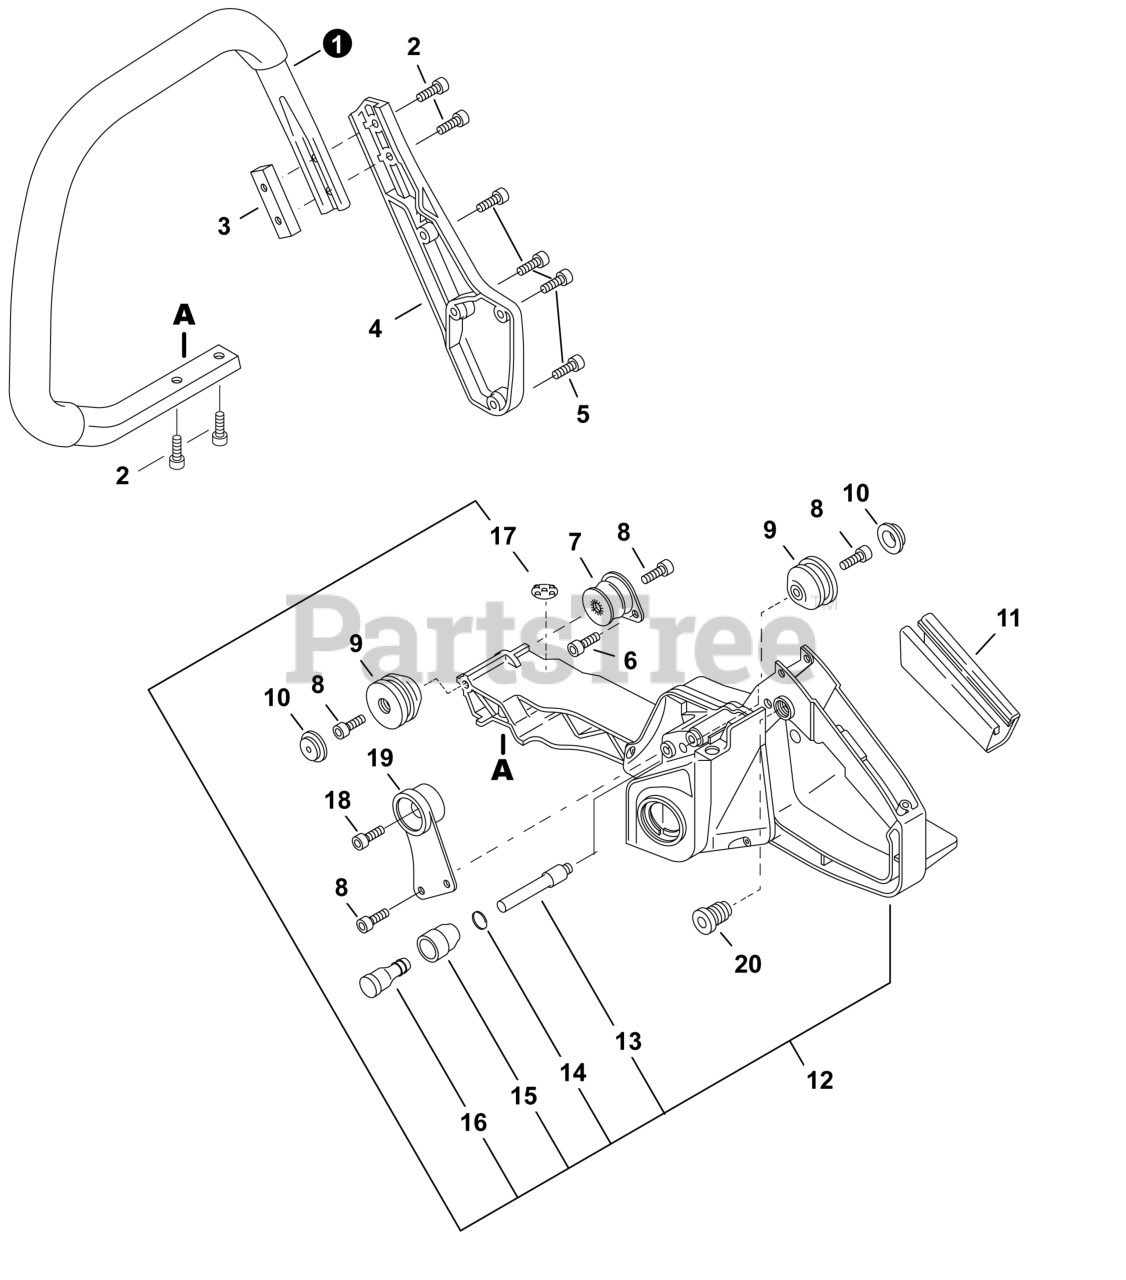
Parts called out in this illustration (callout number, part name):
1	HANDLE, FRONT
2	BOLT 5×20
4	BRACKET, FRONT HANDLE
5	BOLT 5×20
6	BOLT 4×10
8	BOLT 5×14
10	CAP, CUSHION
11	GRIP, HANDLE
12	HANDLE ASSY, REAR - ORANGE
13	PIPE 3×5×90
14	CLIP 5.5
15	HOLDER, VENT
16	VENT ASSY
18	BOLT 5×20
